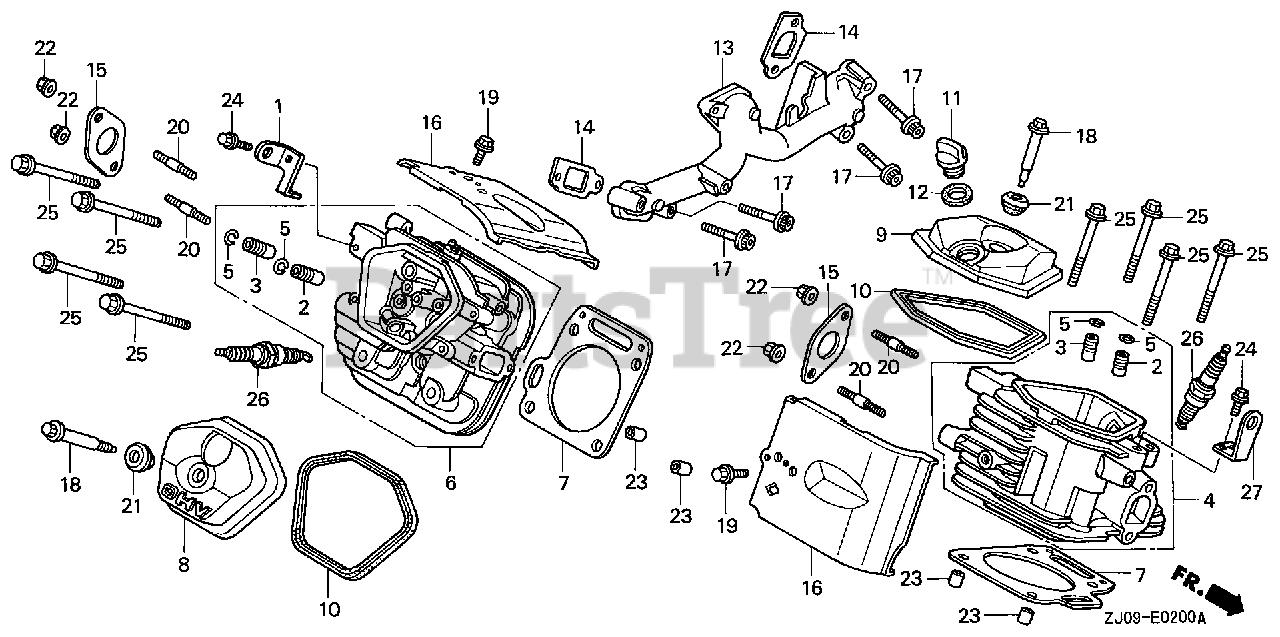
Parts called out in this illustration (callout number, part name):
1	HANGER, ENGINE
2	GUIDE, VALVE (OS)
3	GUIDE, EX. VALVE (OS)
4	CYLINDER HEAD (#1)
5	CLIP, VALVE GUIDE
6	CYLINDER HEAD (#2)
7	GASKET, CYLINDER HEAD
8	COVER, HEAD
9	COVER, HEAD FILLER
10	GASKET, CYLINDER HEAD COVER
11	CAP, OIL FILLER
12	GASKET, OIL FILLER CAP
13	MANIFOLD, IN.
14	GASKET, IN. MANIFOLD
15	GASKET, EX. PIPE
15	GASKET, EX. PIPE (WACKER)
16	SHROUD, HEAD
17	BOLT, SOCKET (8X45)
18	BOLT, HEAD COVER
19	BOLT, FLANGE (6X14)
20	BOLT, STUD (8X22)
21	WASHER, HEAD COVER
22	NUT, FLANGE (8MM)
23	PIN A, DOWEL (12X20)
24	BOLT, FLANGE (8X20)
25	BOLT, FLANGE (10X80)
26	SPARK PLUG (BPR2ES) (NGK)
26	SPARK PLUG (J14CR-U)
26	SPARK PLUG (ZGR4A) (NGK)
26	SPARK PLUG (J16CR-U)
26	SPARK PLUG (ZGR5A) (NGK)
27	HANGER, ENGINE
